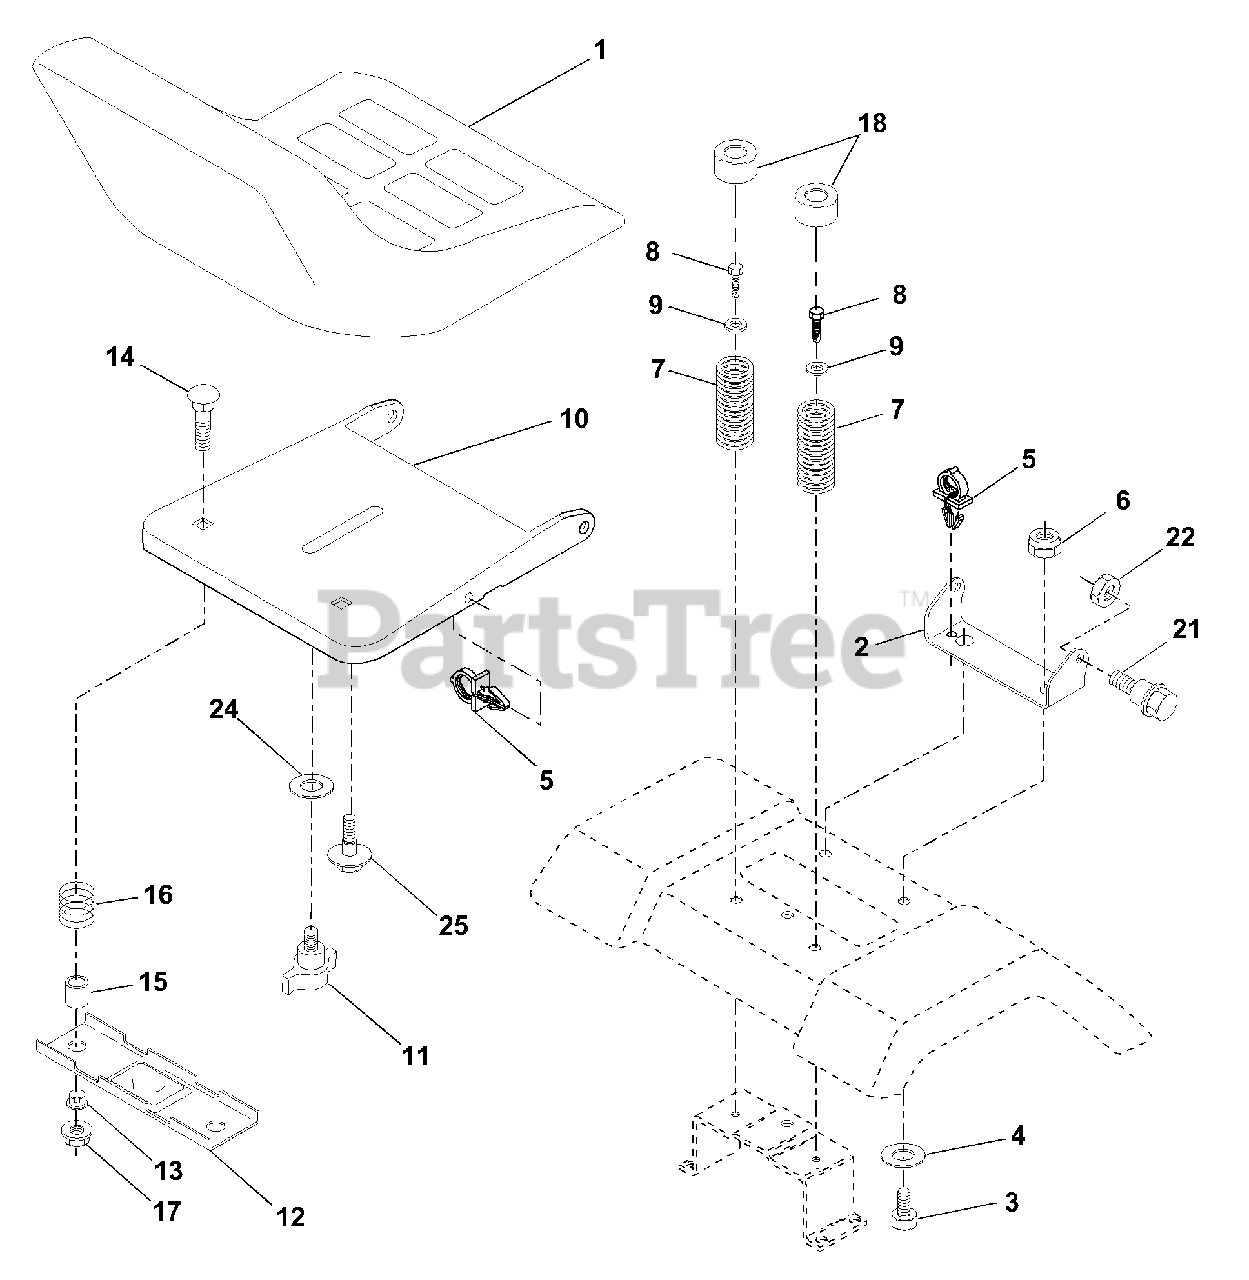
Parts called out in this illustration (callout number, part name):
1	Seat
2	Bracket Pivot Seat 8 720
3	Bolt Fin Hex 3/8-16unc X 1
4	Washer 13/32 X 1 X 10 Ga
5	Clip Push-In
6	Nut Hex w/Ins. 3/8-16 Unc
7	Spring Seat Cprsn 2 250 Blk Zi
8	Screw Thdrol 3/8-16 X 1-1/2
9	Washer 13/32 X 1 X 14 Ga.
10	Pan Seat
11	Knob Seat Adj Wingnut
12	Bracket Mounting Switch
13	Bushing Snap Blk Nyl 50 Id
14	Bolt Rdhd Sqnk 1/4-20 x 1-1/2
15	Spacer Split 28 x 96 Yel Zinc
16	Spring Cprsn 1 27 Blk Pnt
17	Nut Lock 1/4 Lge Flg Gr 5 Zinc
18	Cap Spring Seat
21	Bolt Shoulder 5/16-18 Unc
22	Nut Hex Lock W/Ins 5/16-18
24	Washer 17/32 X 1-3/16 X 12 Ga.
25	Bolt Shoulder 5/16-18 X 62
